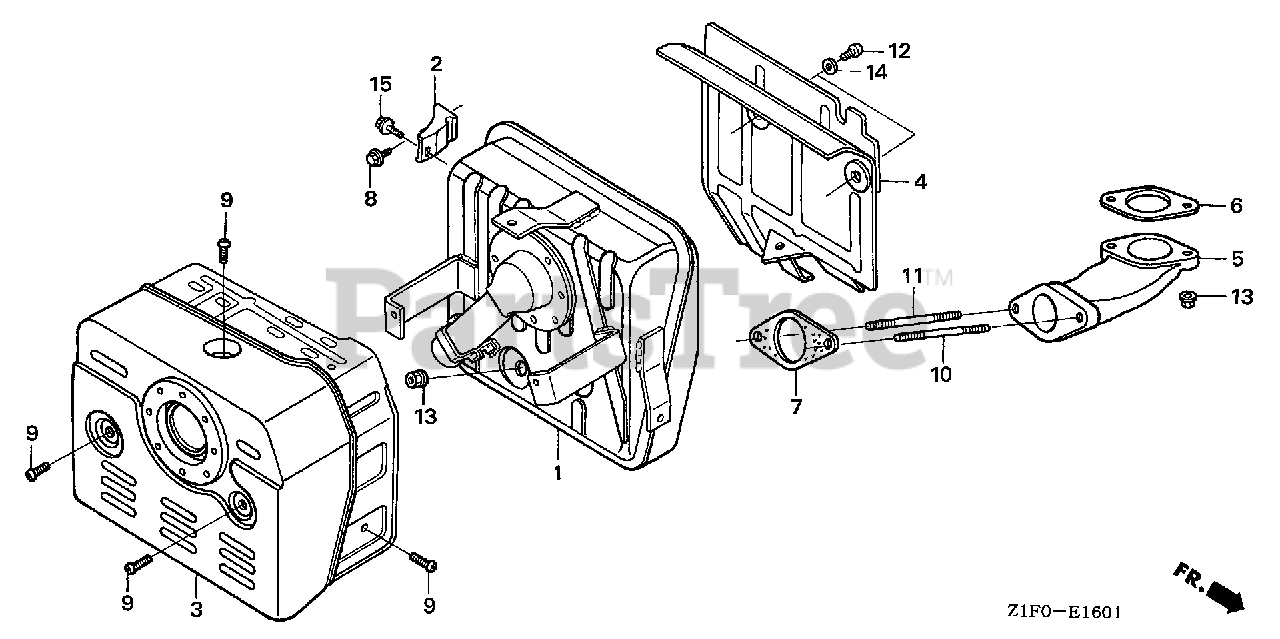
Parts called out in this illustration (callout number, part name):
1	MUFFLER (NOT AVAILABLE)
2	STAY, MUFFLER
3	PROTECTOR, MUFFLER (NOT AVAILABLE)
4	SEPARATOR, MUFFLER
5	PIPE, EX.
6	GASKET, EX. PIPE Use up to Engine SN 2949254.
6	GASKET, EX. PIPE (WACKER)
6	GASKET, EX. PIPE
7	GASKET, EX. PIPE
8	BOLT, FLANGE (8X16)
9	SCREW, TAPPING (5X8)
10	BOLT, STUD (8X60)
11	BOLT, STUD (8X70)
12	SCREW, PAN (6X6)
13	NUT, FLANGE (8MM)
14	WASHER, PLAIN (6MM)
15	BOLT, FLANGE (8X14)
